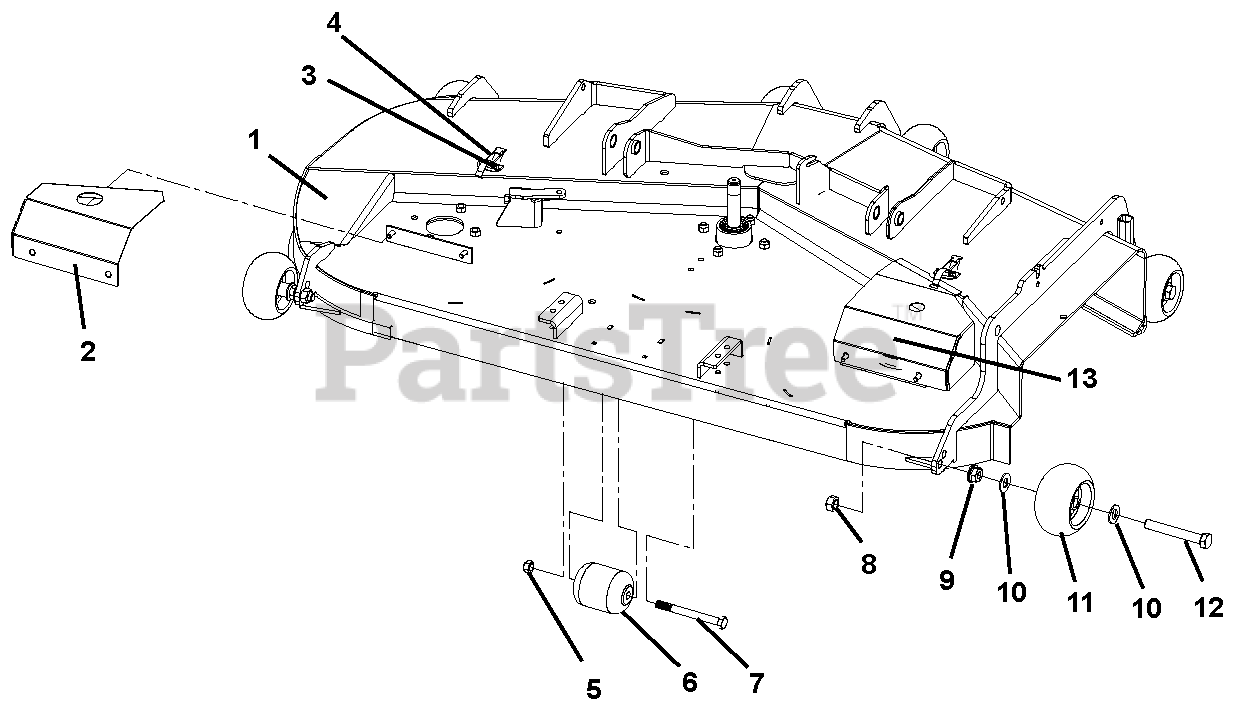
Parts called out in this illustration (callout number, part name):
1	Assembly, 54" Deck w/Decals
2	Shield, Deck LH Belt - 60"
3	Latch, Overcenter
4	Rivet, Pop .753 x .878 x .750
5	Nut, Locking, Cone
6	Roller, Ø3.00 x 3.88
7	Bolt, Hex .38-16 x 2.25
8	Nut, Locking, Top .62-11 (ND)
9	SRATD Flange Hex Nut 518-11
10	Washer, Flat, Steel .656 x 1.31 x .095
11	Wheel, Gauge - Ø5.00 x 2.76
12	Bolt, 5/8-11 x 4.25 Hex 5
13	Shield, RH 54" and 60" Belt (992220, 221)
